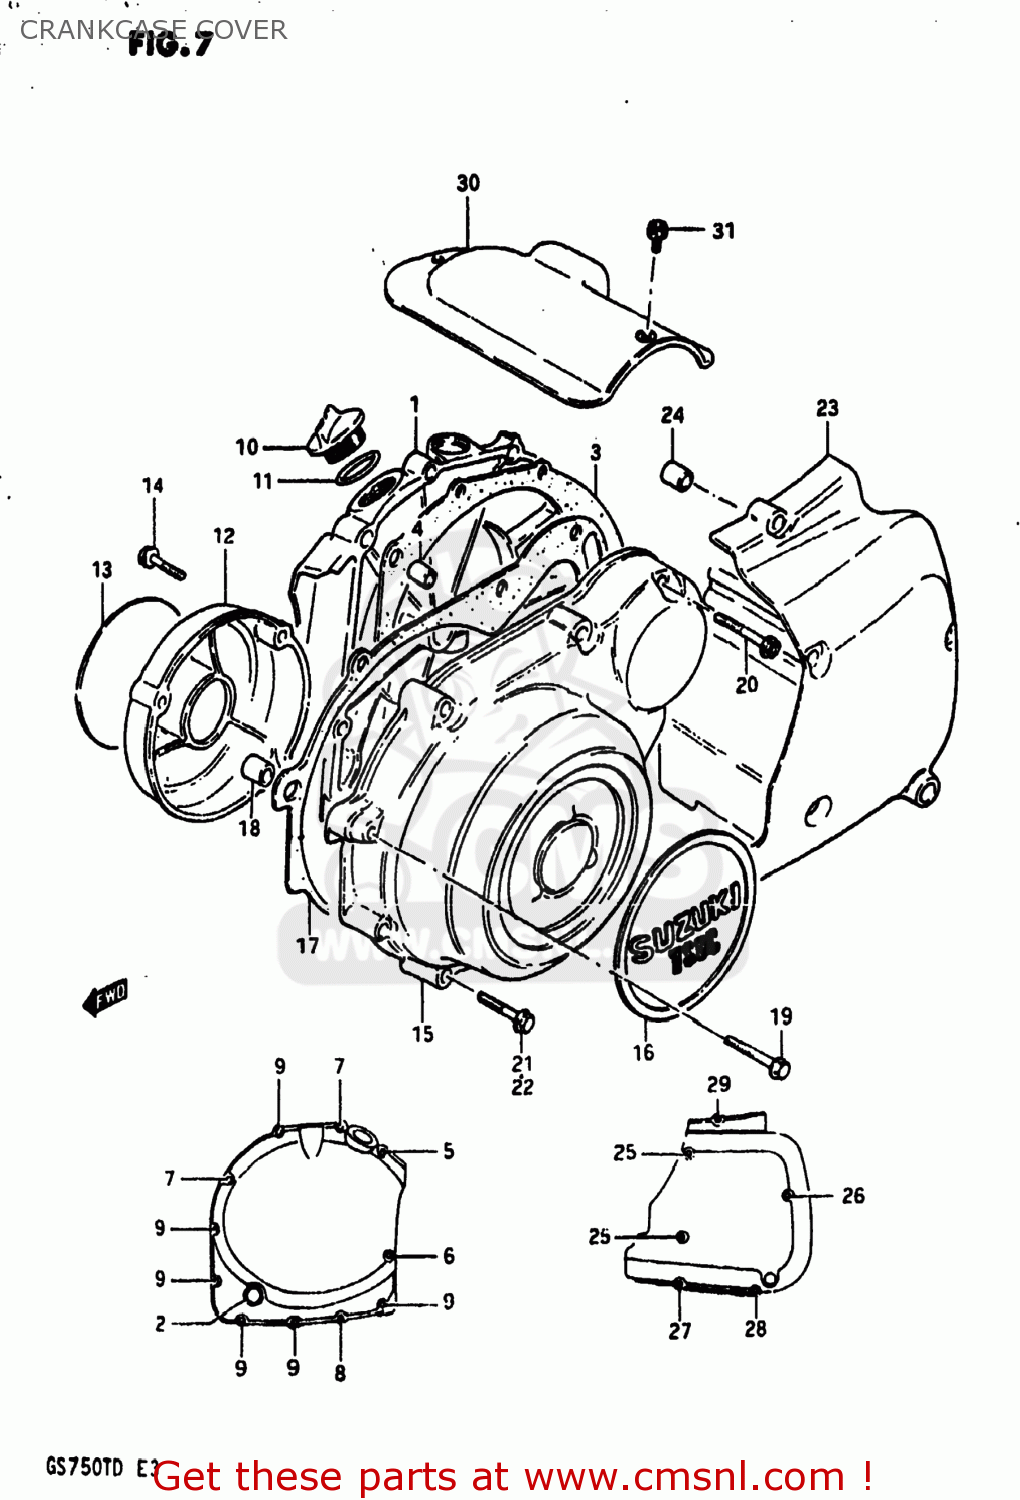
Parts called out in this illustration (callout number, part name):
1	COVER,CLUTCH
2	LENS,OIL LEVEL CHECK
3	GASKET,CLUTCH COVER (MCA)
4	PIN
5	BOLT (6X40)
6	BOLT (6X35)
7	BOLT (6X30)
8	BOLT
9	BOLT (6X20)
10	CAP
11	O RING(D:2.2,ID:32)
12	COVER,CONTACT BREAKER
13	EMBLEM
14	BOLT (5X30)
15	COVER,MAGNETO
16	EMBLEM,MAGNETO COVER
17	GASKET,MAGNETO COVER (MCA)
18	PIN
19	BOLT
20	BOLT (6X40)
21	BOLT (6X35)
22	BOLT (6X30)
23	COVER,ENGINE SPROCKET
24	PIN
25	BOLT 6X95
26	BOLT (6X85)
27	BOLT (6X70)
28	BOLT (6X55)
29	BOLT (6X30)
30	COVER,STARTER MOTOR
31	BOLT
